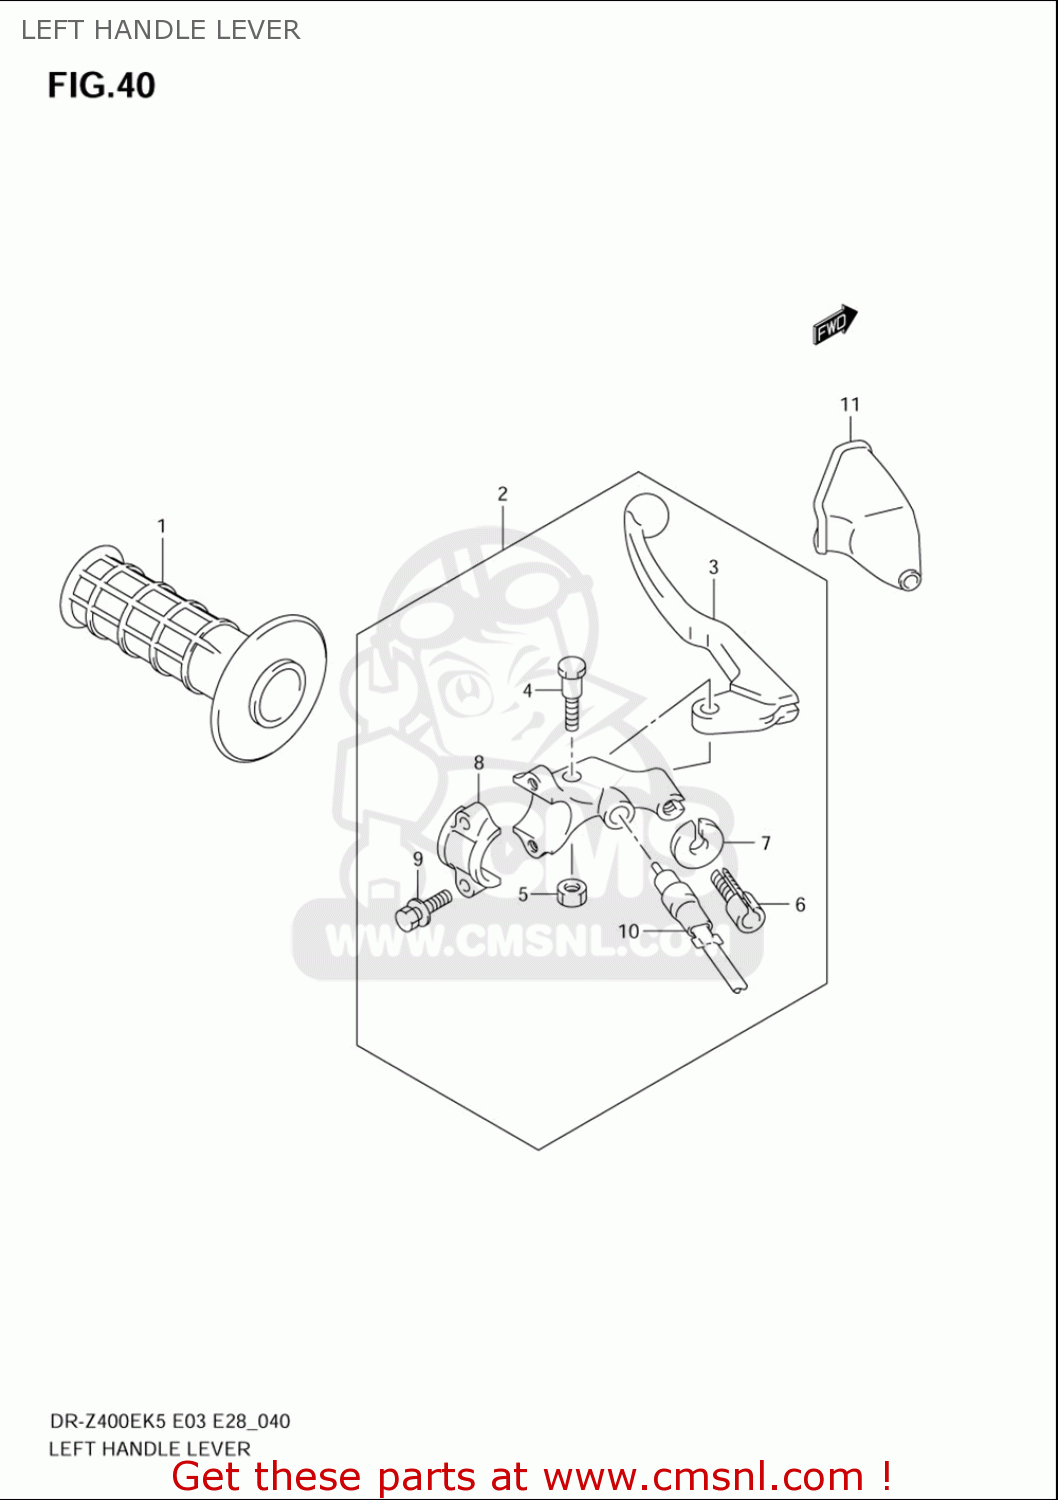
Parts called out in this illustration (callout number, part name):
1	GRIP,L
2	LEVER ASSEMBLY,CLUTCH
3	LEVER,CLUTCH
4	BOLT,LEVER PIVOT
5	NUT 6MM
6	ADJUSTER,WIRE
7	NUT,LOCK
8	BRACKET,HOLDER
9	BOLT,BRACKET
10	SWITCH ASSEMBLY,CLUTCH
11	COVER,CLUTCH CABLE DUST
